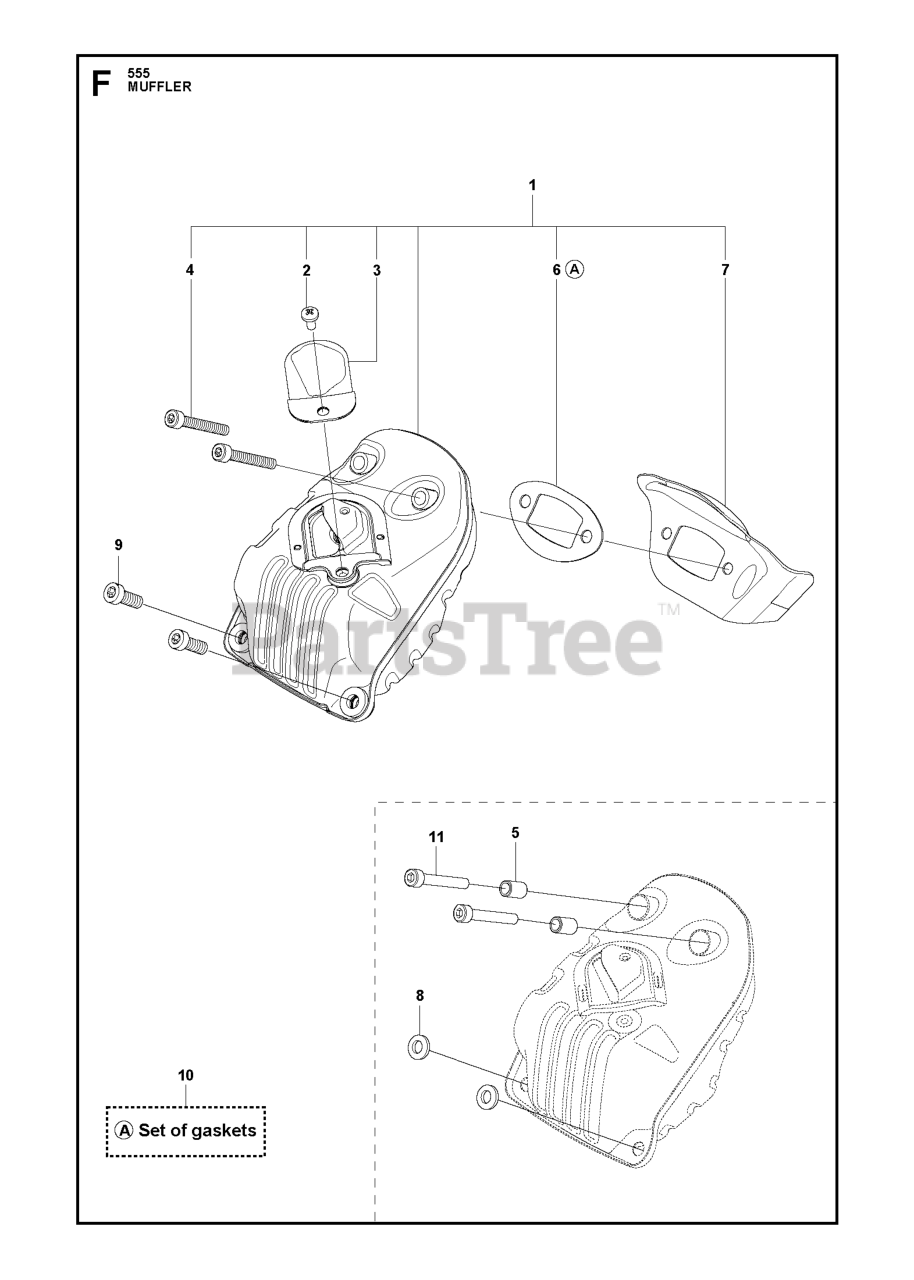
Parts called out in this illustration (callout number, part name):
1	MUFFLER KIT
3	SPARK ARRESTER
4	SCREW ITXSCM M6X50 T27 12.9 T
5	SLEEVE
6	GASKET MUFFLER
7	HEAT DEFLECTOR
8	WASHER
9	SCREW ITXSCM M6X20 T27 10.9 Z
10	GASKET KIT
11	SCREW
